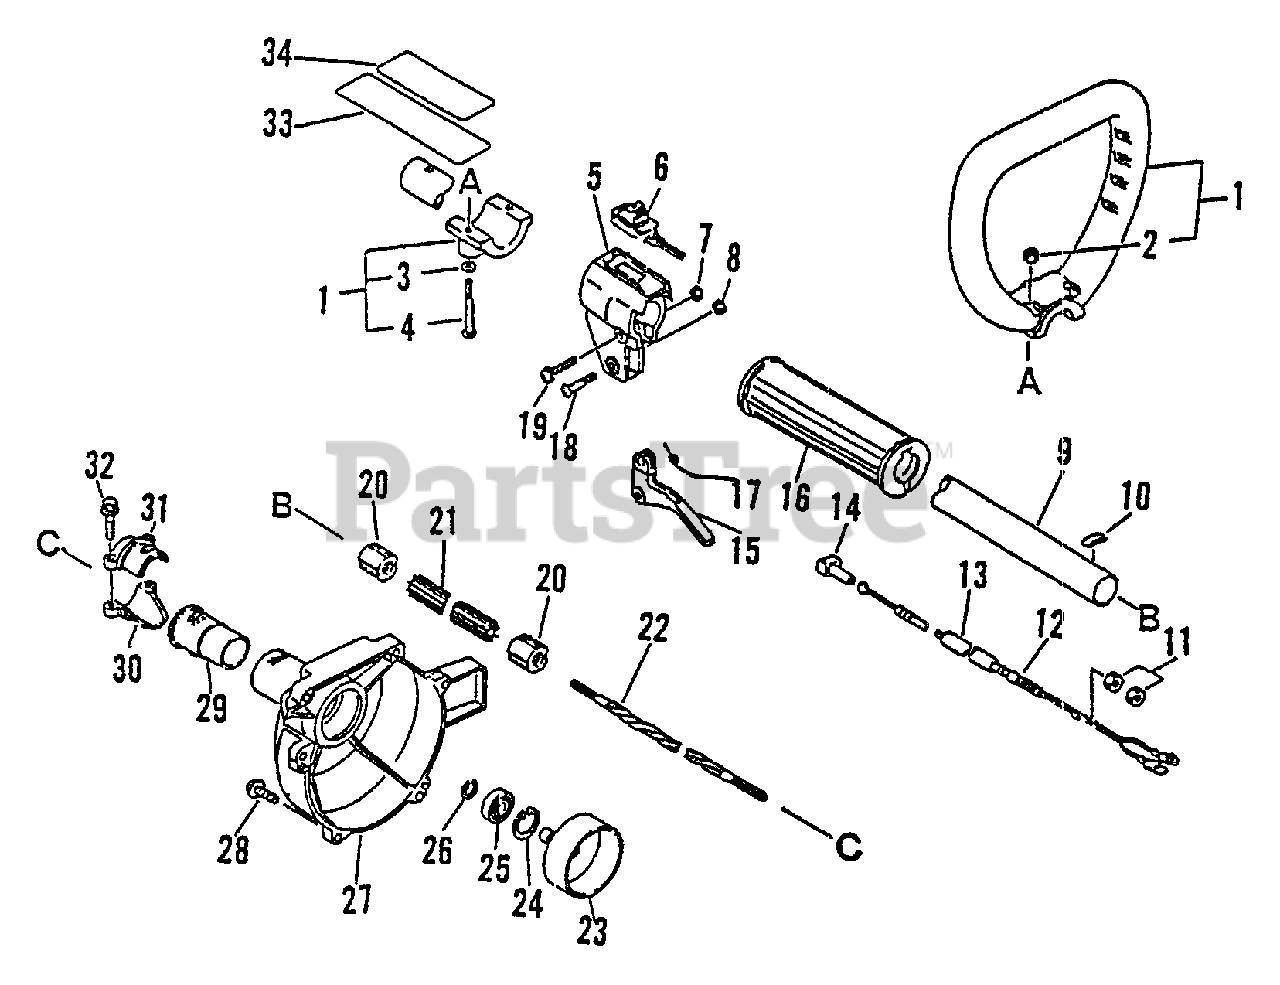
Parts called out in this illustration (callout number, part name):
1	LOOP HANDLE ASSY
3	WASHER - 5
4	SCREW - 5X40
5	BRACKET, THROTTLE CONTROL
6	IGNITION SWITCH ASSY
8	LOCKNUT - 5
9	MAIN PIPE ASSY
10	LABEL - ALIGNMENT
12	CABLE, THROTTLE
13	TUBE - VINYL
14	GUIDE, CABLE
15	TRIGGER, THROTTLE
16	GRIP, HANDLE
17	SPRING, TRIGGER
18	SCREW - 5X30
19	SCREW - 5X30
21	LINER - FLEXIBLE
22	DRIVESHAFT - FLEXIBLE
23	DRUM, CLUTCH
24	RING, RETAINING - 28
25	BEARING, BALL - 6201
26	RING, RETAINING - 12
27	CASE, FAN
28	SCREW - 4X16
30	CLAMP, MAIN PIPE
31	CLAMP, MAIN PIPE - UPPER
32	BOLT - 5X25
33	LABEL - CAUTION
34	LABEL - CAUTION
